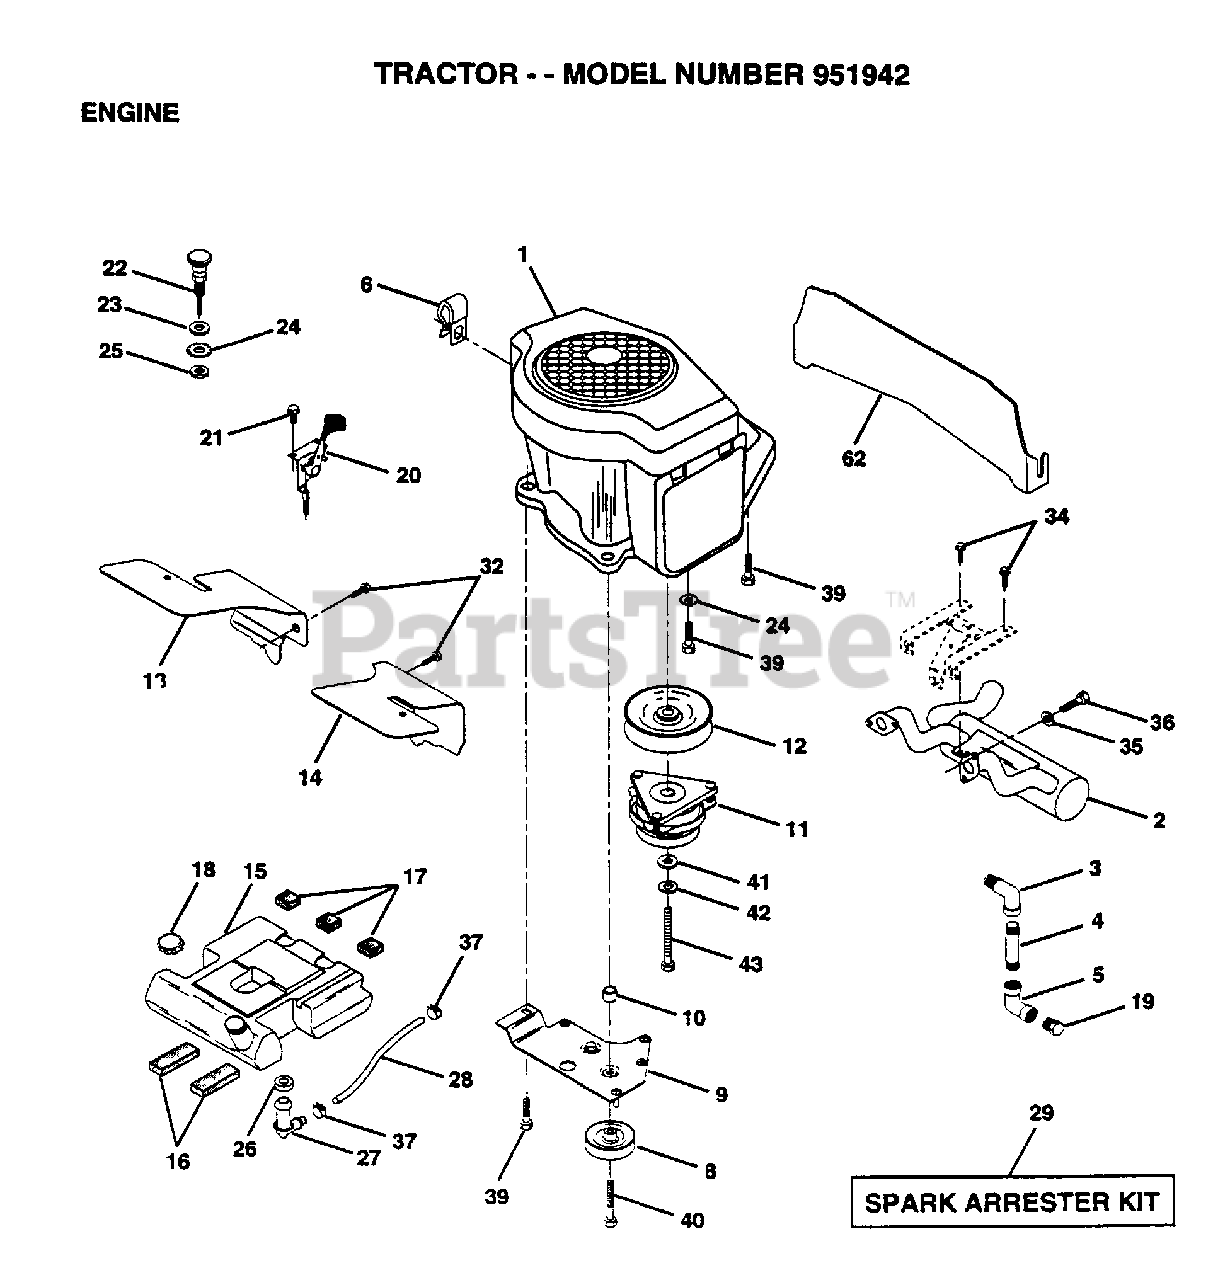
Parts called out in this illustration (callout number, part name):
1	ENGINE KOHLER MODEL
2	MUFFLER.KOH.VCT.
3	STREET ELBOW LT
4	PIPE NIPPLE
5	ELBOW
6	CLAMP.TUBE.DBL.EN
10	BUSHING.
12	PULLEY.ENGINE.VGT
13	BAFFLE.AIR.LH.K
16	PAD IDLER TI
17	PAD-SPACER LT
18	CAP ASM FUEL
19	PLUG T
20	CONTROL THTL 37
21	SCREW LT
22	"CONTROL.CHOKE.51"""
23	WASHER
24	LOCKWASHER
26	BUSHING OUTLET T
27	STEM.TANK.FUEL
29	SPARK ARREST KIT
32	SCREW LT
34	SCREW
35	LOCKWASHER
36	SCREW
37	HOSE CLAMP
39	SCREW LT
40	SCREW.3/8-16X3.25
41	WASHER
42	LOCKWASHER
62	SHIELD.HEAT.MUF
